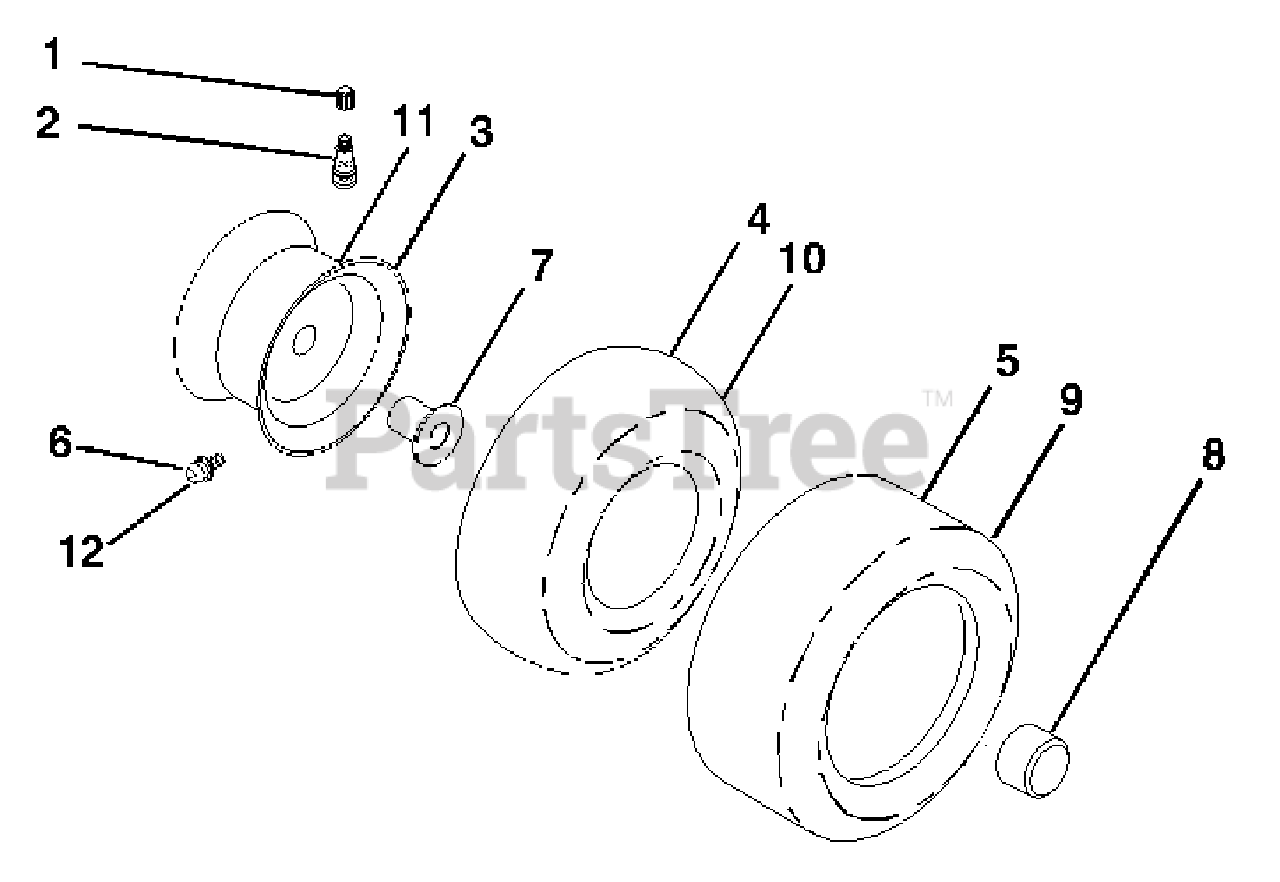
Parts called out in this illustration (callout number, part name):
1	Cap, Valve, Tire
2	Stem, Valve
3	Rim Assembly, Front
4	Tube, Front (Service Item Only)
5	Tire, Front
6	Fitting, Grease
7	Bearing, Flange (Front Wheel Only)
8	Cap, Hub
9	Tire, Rear
10	Tube, Rear (Service Item Only)
11	Rim Assembly, Rear
12	Fitting, Grease
